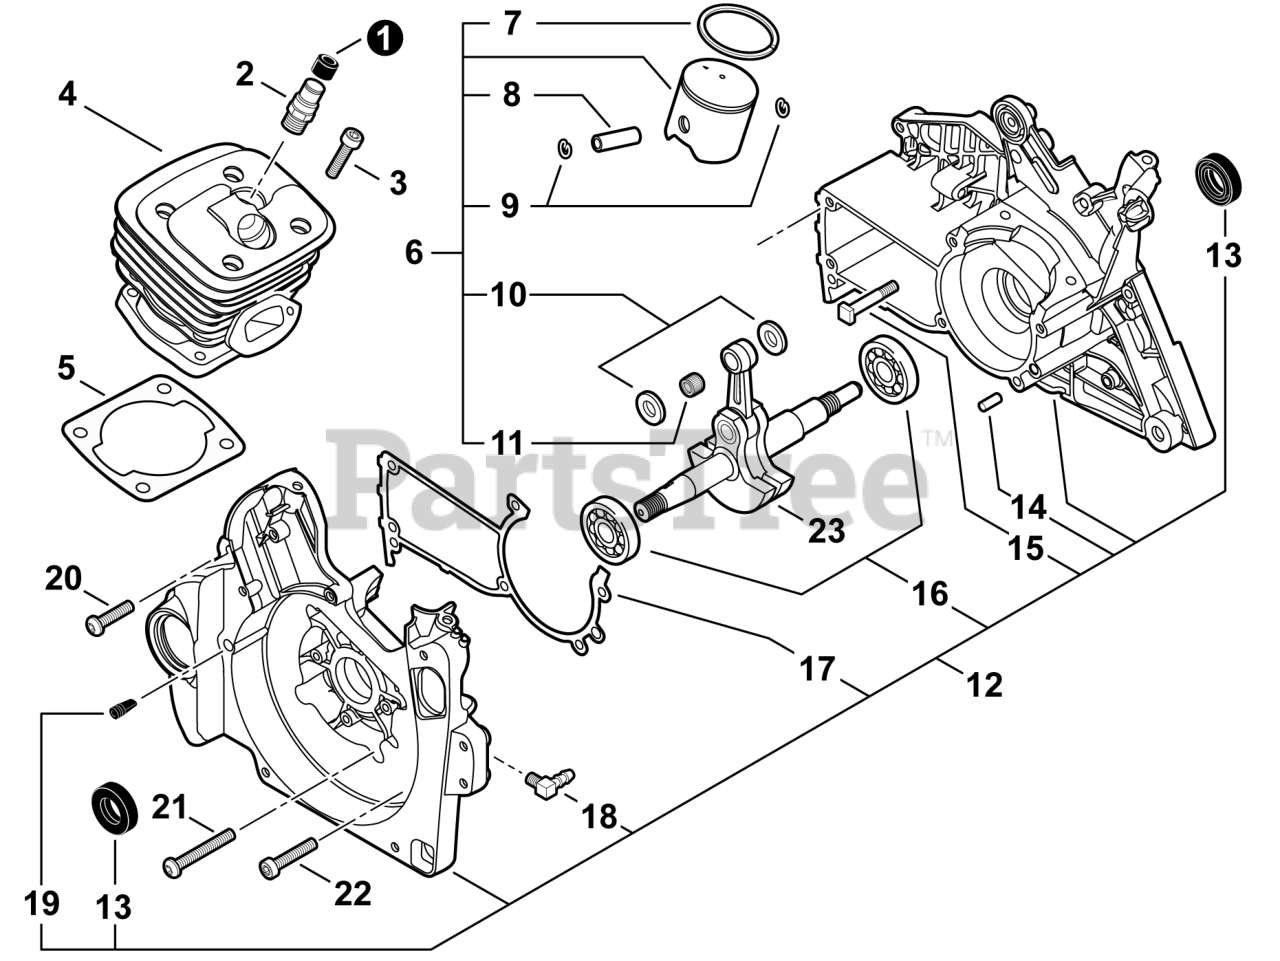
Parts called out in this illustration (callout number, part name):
1	COVER, DUST
2	VALVE ASSY, DECOMPRESSION
3	BOLT, TORX 5x25
4	CYLINDER
5	GASKET, CYLINDER
6	PISTON KIT
7	RING, PISTON
8	PIN, PISTON
9	RING, SNAP 11
10	WASHER, THRUST
11	BEARING, NEEDLE 11
12	CRANKCASE SET
13	SEAL, OIL 15
14	PIN, LOCATING 5x10
15	STUD, GUIDE BAR 8
16	BEARING, BALL 6202
17	GASKET, CRANKCASE
18	CONNECTOR, PIPE
19	VENT ASSY
20	BOLT, TORX 5x20
21	BOLT, TORX 5x35
22	BOLT, TORX 5x25
23	CRANKSHAFT ASSY
